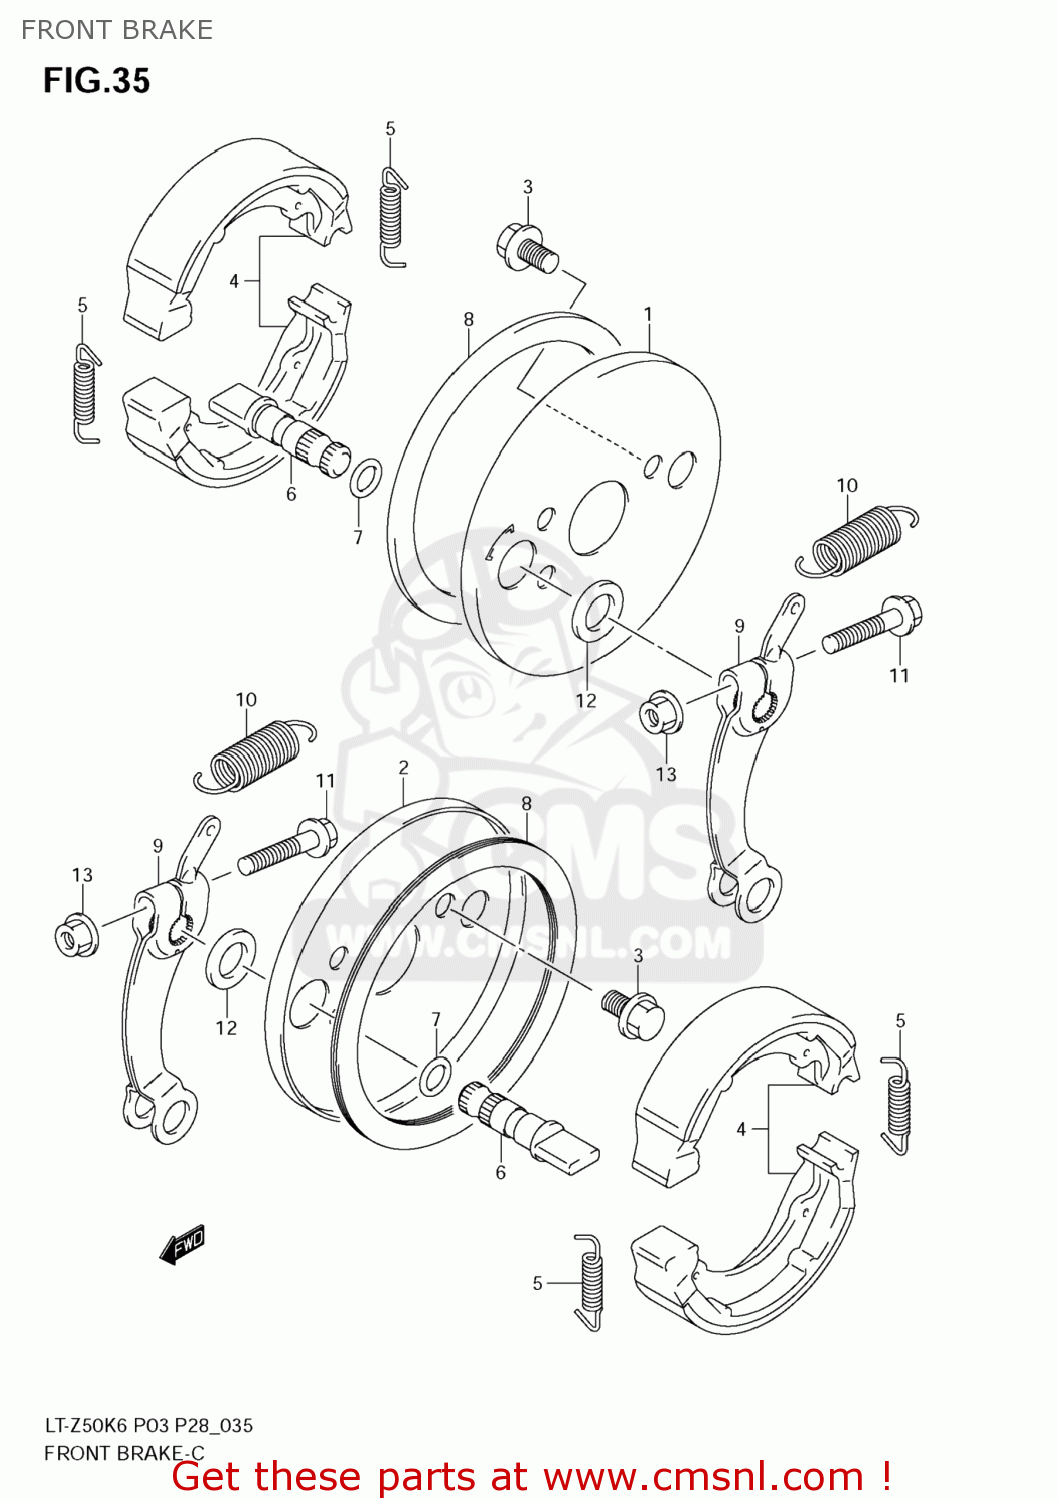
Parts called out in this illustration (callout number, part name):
1	PLATE,FR BRAKE,R
2	PLATE,FR BRAKE,L
3	BOLT
4	SHOE SET,BRAKE (NAS)
5	SPRING
6	CAM,FR BRAKE
7	O RING(D:1.9,ID:9.8)
8	SEAL,FR BRAKE DUST
9	LEVER,FR BRAKE CAM
10	SPRING
11	BOLT(5X27)
12	WASHER
13	NUT
